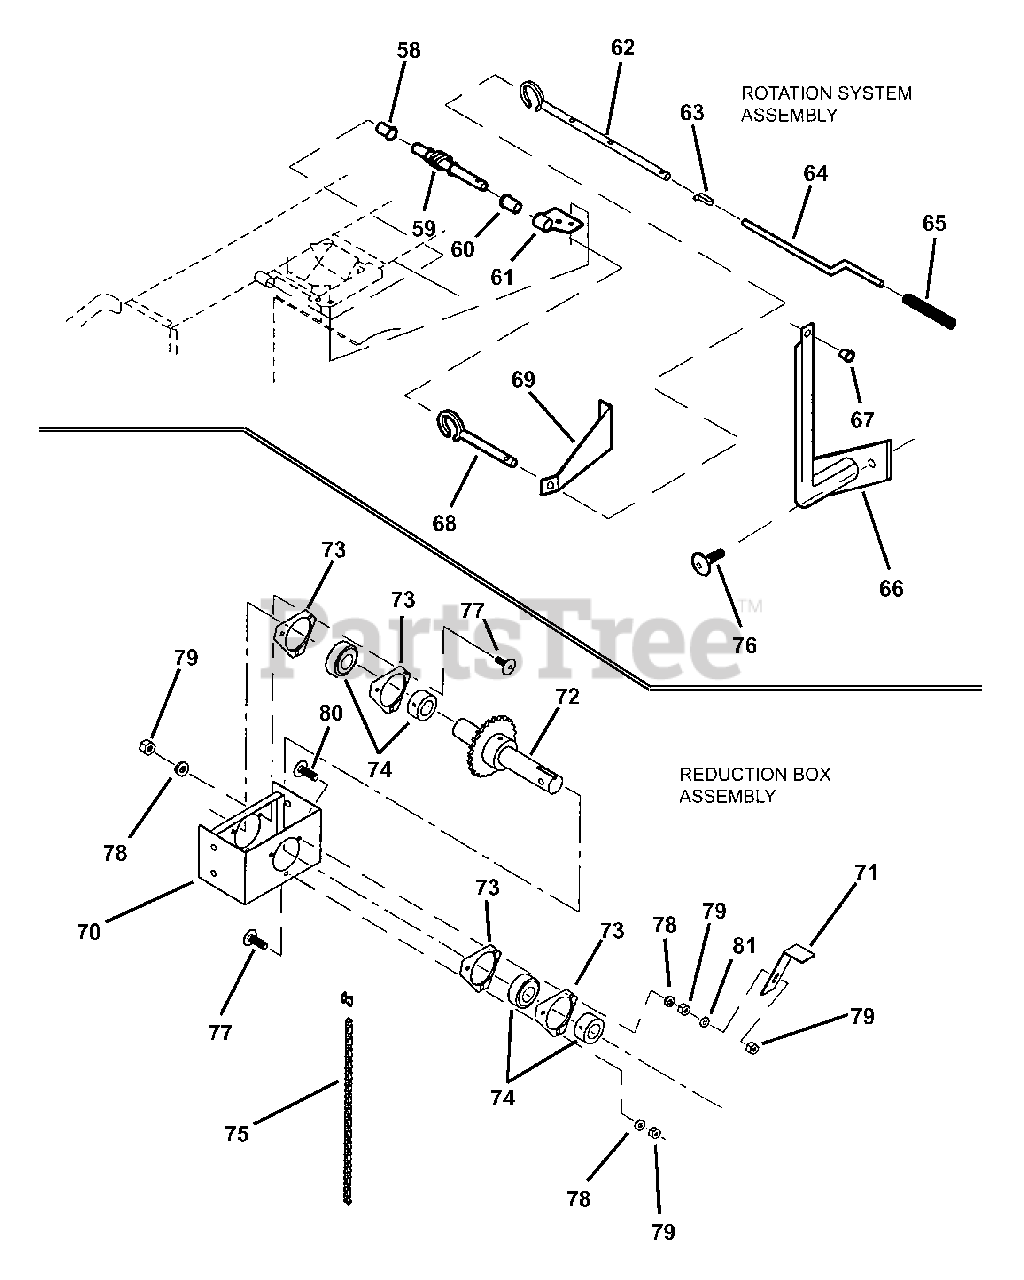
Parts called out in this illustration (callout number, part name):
58	BUSHING, 1-5/16" long (plastic)
59	WORM, Rotation
60	BUSHING, 1-11/16" long (plastic)
61	SUPPORT, Rotation Worm
62	TUBE, Handle
63	BUTTON, Snap
64	HANDLE, Rotation
65	GRIP, Handle
66	SUPPORT, Rotation Handle
67	GROMMET
68	TUBE, Extension (for models with Briggs Vanguard engine)
69	BRACKET, Support (for models with Briggs Vanguard engine)
70	REDUCTION BOX
71	GUIDE, Pulley
72	ASSEMBLY, Sprocket with Shaft
73	FLANGE, Bearing
74	BEARING w/Set Screws
76	BOLT, 3/8-16 x 1-1/4" Square Neck Carriage
77	BOLT, 5/16-18 x 5/8" Square Neck Carriage, Grade 5
78	WASHER, 5/16" Lock
79	NUT, 5/16-18 Hex, Grade 5 or B
80	BOLT, 5/16-18 x 1" Square Neck Carriage
81	WASHER, 3/8" Internal Tooth Lock
